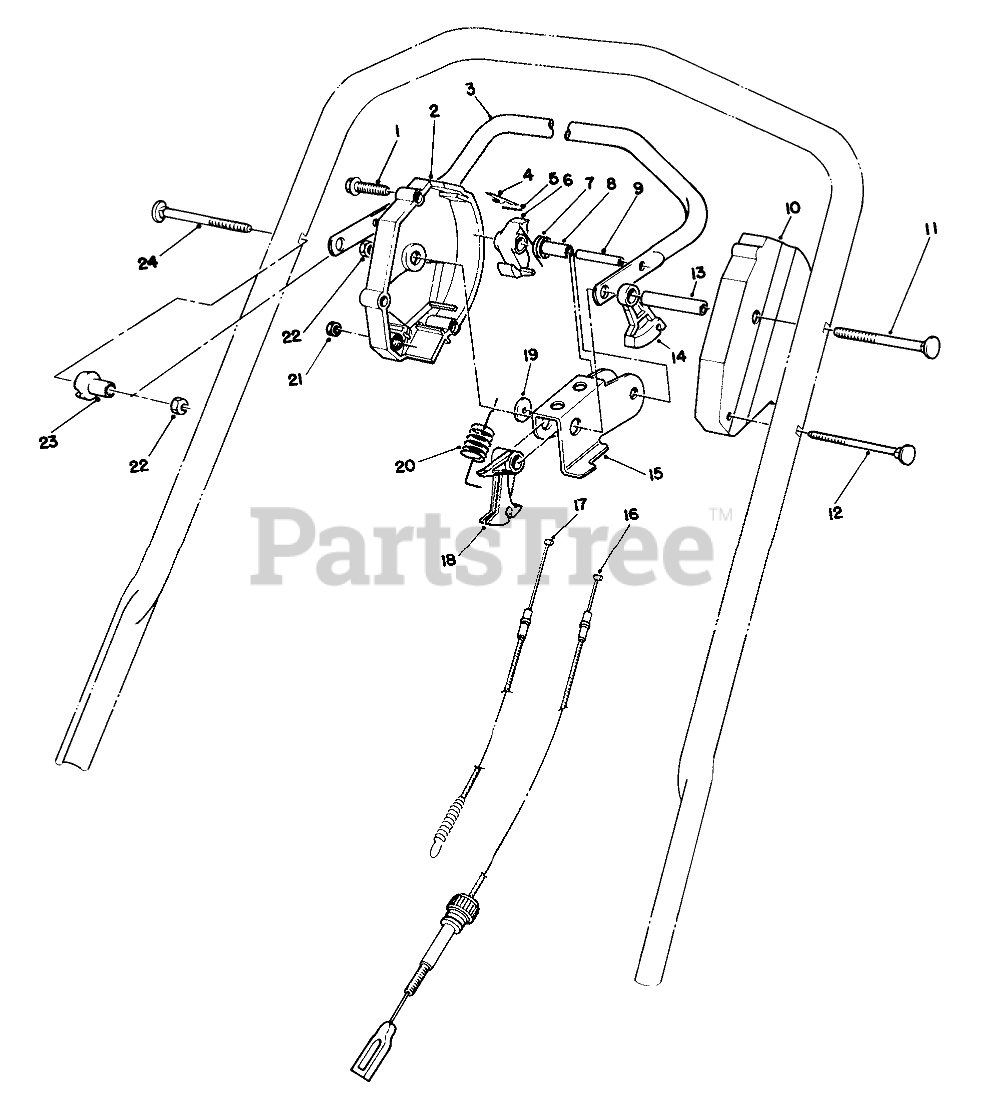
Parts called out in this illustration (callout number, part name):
1	SCREW-HWHTF
2	Housing Control R.H.
3	Bar-Control
4	SPRING-LEAF
5	PIN-INSERT
6	HOOK-CONTROL
7	SPRING-TORSION
8	SPACER
9	PIN-ROLL, SLOTTED
10	HOUSING-CONTROL, LH
11	5/16-18 X 3 HNDLE SCREW
12	HANDLE SCREW
13	TUBING-SPACER
14	LEVER-TRACTION
15	Rocker
16	TRACTION CABLE
17	Cable-Clutch
18	LEVER-CABLE
19	PLASTIC WASHER
20	Spring-Detent
21	NUT-LOCK, NI
21	NUT-HEX
22	NUT-LOCK, NI
23	SPACER-SUPPORT
24	5/16-18 X 2 HNDLE SCREW
